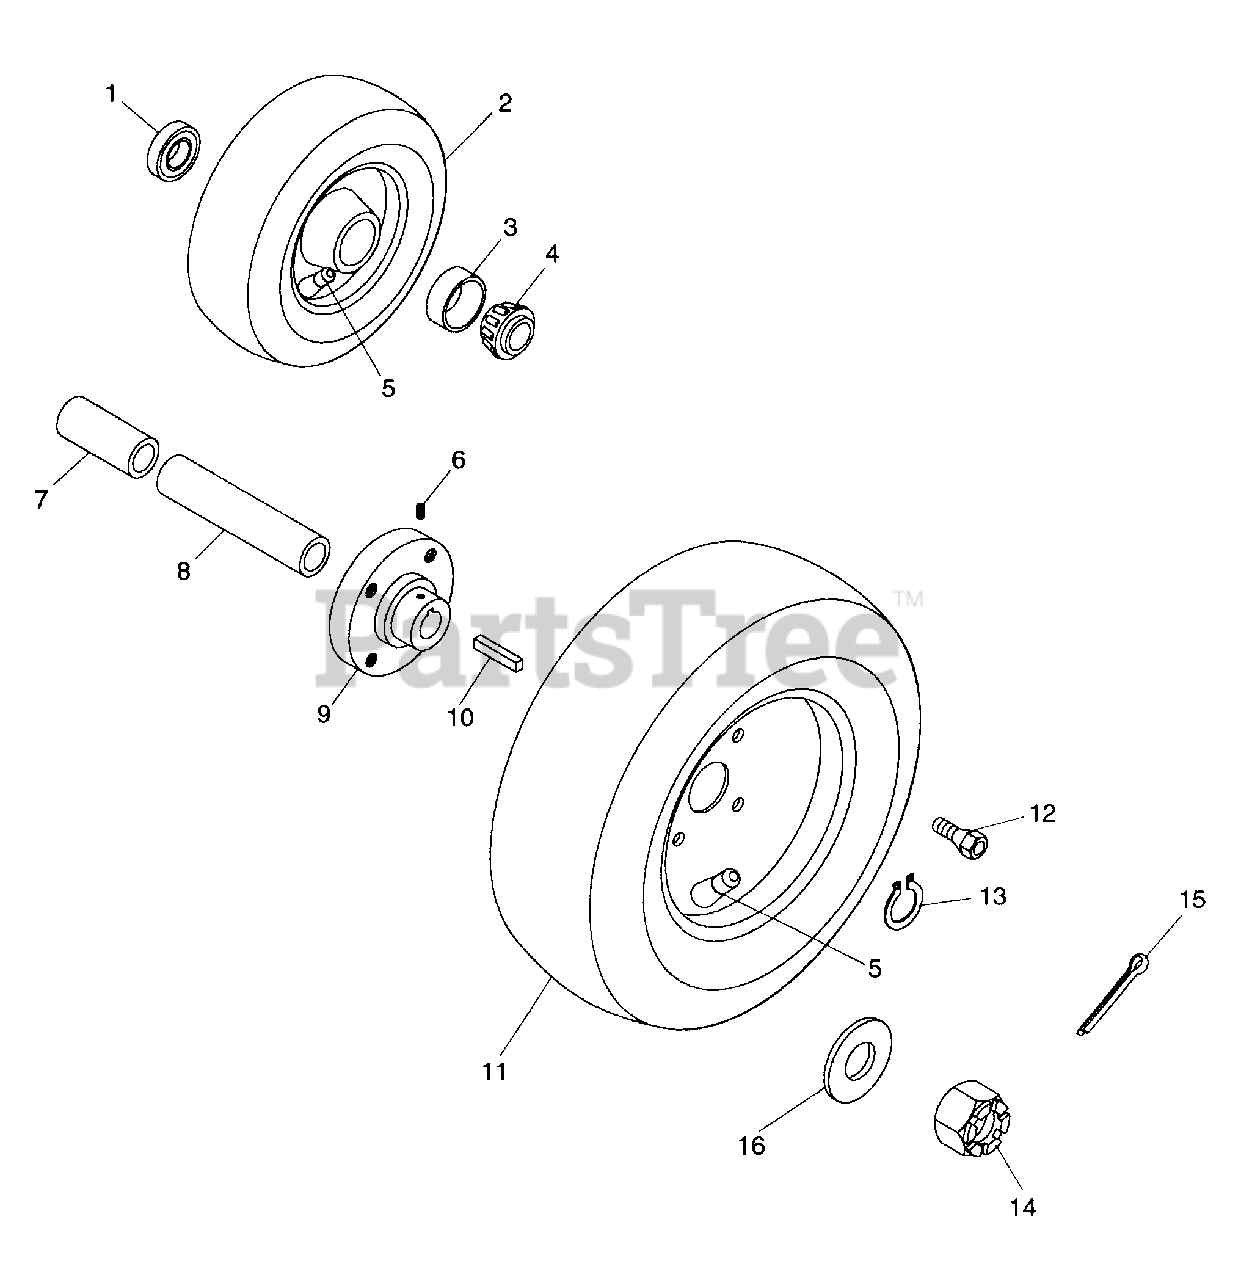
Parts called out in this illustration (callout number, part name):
1	Seal
2	Tire/Wheel Assembly 4.80-8
3	Bearing-Cup 1.980 x 4.20
4	Bearing-Cone 1.0 x .58
5	Valve Stem Assembly
6	Screw-Set .25-20 x .25
7	Spacer
8	Spacer
9	Hub
10	Key-Square .248 x 1.75 x .248
10	Key-Woodruff .25 x 1.0 x 7.00
11	Tire/Wheel Assembly 8.50-8 x 18
12	Bolt-Hex .50-20 x .75 x 1.62
13	Ring-Retaining-External .906 x .078
14	Nut-Hex-Slotted .75-20
15	Pin-Cotter .12 x 1.25
16	Washer-Flat-Steel .813 x 1.370 x .100
